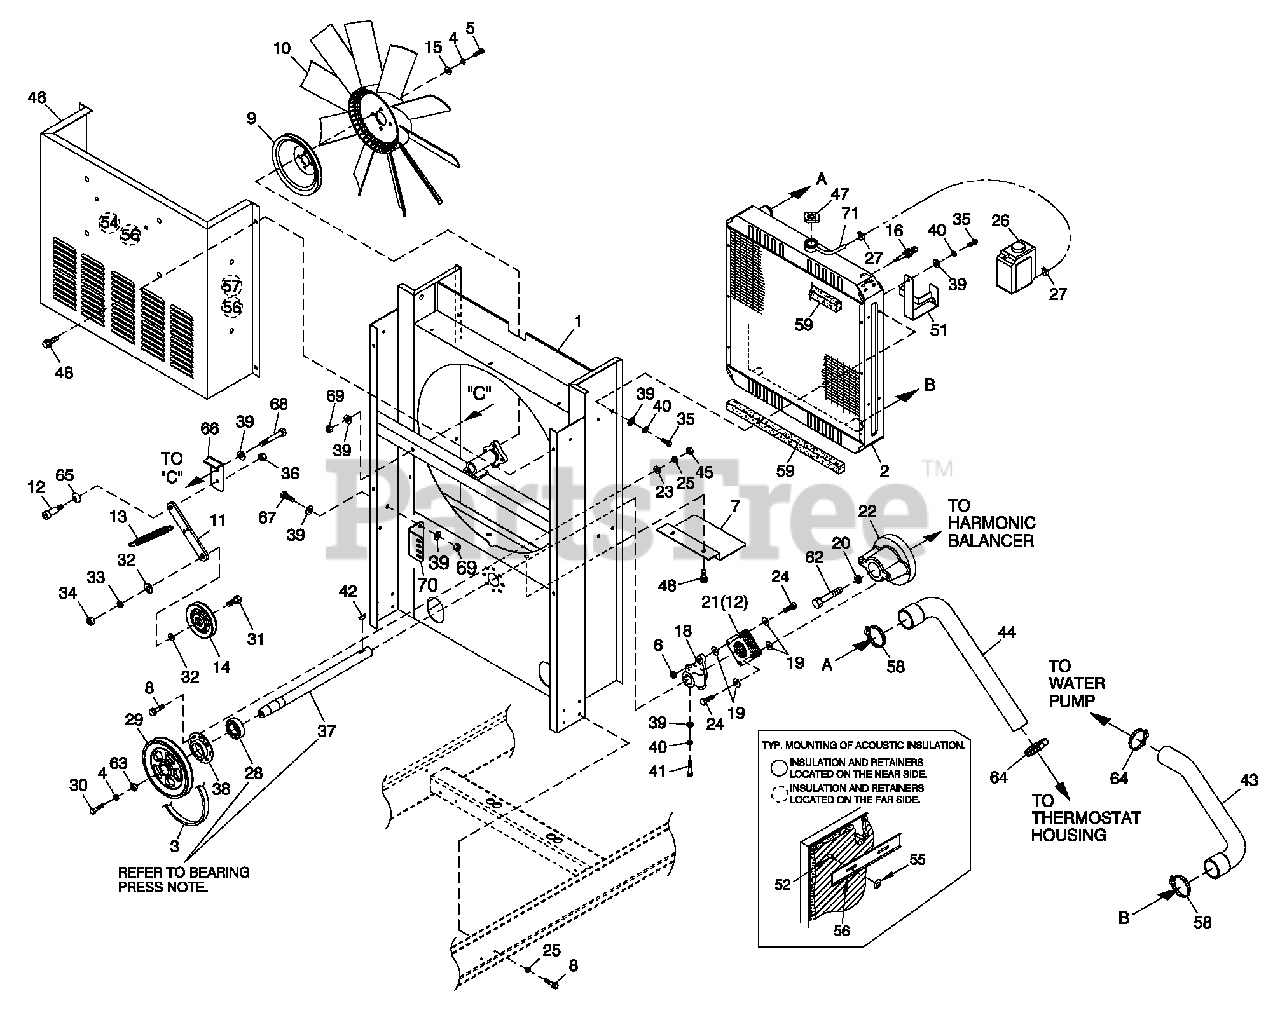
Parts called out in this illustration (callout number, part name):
1	WELDMENT RADIATOR SUPPORT C4
2	RADIATOR 598 X 568 X 49 CPL LH
3	V- BELT 31/64" X 57-3/8"
4	WASHER LOCK M10
5	SCREW HHC M10-1.5X30G10.9
6	NUT HEX LOCK 5/16-24 NY INS
7	SHIELD RADIATOR C4
8	SCREW HHFC M6-1.0X20G8.8
9	PULLEY FAN V-GROOVE 9"
10	FAN COOL 22" DIA 10 BLADE LH
11	FLAT TENSIONER ARM
12	SHOULDER BOLT 3/8 X 1/2"
13	SPRING TENSION
14	PULLEY V- BELT 4" FLANGED
15	WASHER FLAT 3/8-M10 ZINC
16	PRO BE COOLANT LEVEL 3/8 NPTF
18	HU B FLEX PLATE
19	WASHER FLEX (THIN)
20	WASHER LOCK M12
21	DISK FLEX
22	COUPLING FLEX HU B MACHINED
23	WASHER FLAT 1/4-M6 ZINC
24	SCREW HHC 5/16-24X1.124
25	WASHER LOCK M6-1/4
26	TANK COOLANT RECOVERY
27	CLAMP HOSE BAND 1/4
28	BEARING #6205 2NSE C3 E SRI2 S
29	PULLEY 5.5" DIA MACHINED
30	SCREW HHCM10-1.5X30 G8.8
31	SCREW HHC 1/2-13 X 2" G8
32	WASHER FLAT 1/2 ZINC
33	WASHER LOCK 1/2
34	NUT HEX 1/2-13 STEEL
35	SCREW HHFC M8-1.25 X 20 W/M6
36	NUT HEX LOCK 5/16-18 NY INS SS
37	SHAFT FAN DRIVE C4 3.0LG14
38	RETAINER BEARING
39	WASHER FLAT 5/16-M8 ZINC
40	WASHER LOCK M8-5/16
41	SCREW HHC M8-1.25X35 G8.8
42	KEY WOODRUFF 4X19D
43	HOSE RADIATOR LOWER 3.0L G14
44	HOSE RADIATOR UPPER 3.0L G14
45	NUT HEX M6X 1.0 G8YEL CHR
46	INNER DISCHARGE DUCT, C4
47	CAP RADIATOR 13 PSI
48	SCREW THF M6-1 X 16 N WA Z/JS
51	BRACKET COOLANT TANK
52	INSULATION RETAINMENT HANGER
54	INSULATION FRONT INNER DUCT
55	WASHER SELF LOCKING DOME
56	RETAINER INSULATION (450)
57	INSULATION INNER DUCT
58	CLAMP HOSE #28 1.32-2.25
59	TAPE FOAM 1 X 1 (26.75" LG)
62	SCREW HHCM12-1.5X75 G8.8
63	SPACER .5 X 1.5 X .25 STL/ZINC
64	CLAMP HOSE #24 B1.06-2.00
65	WASHER BELLEVILLE .75X.38X.028
66	TENSIONER ARM SUPPORT BENT 90
67	SCREW HHC M8-1.25X20 C8.8
68	SCREW HHC M8-1.25X75 C8.8
69	NUT HEX LOCK M8-1.25 NY INS
70	BRACKET TENSIONER SPRING
71	HOSE 9/32 ID (27" LG)
